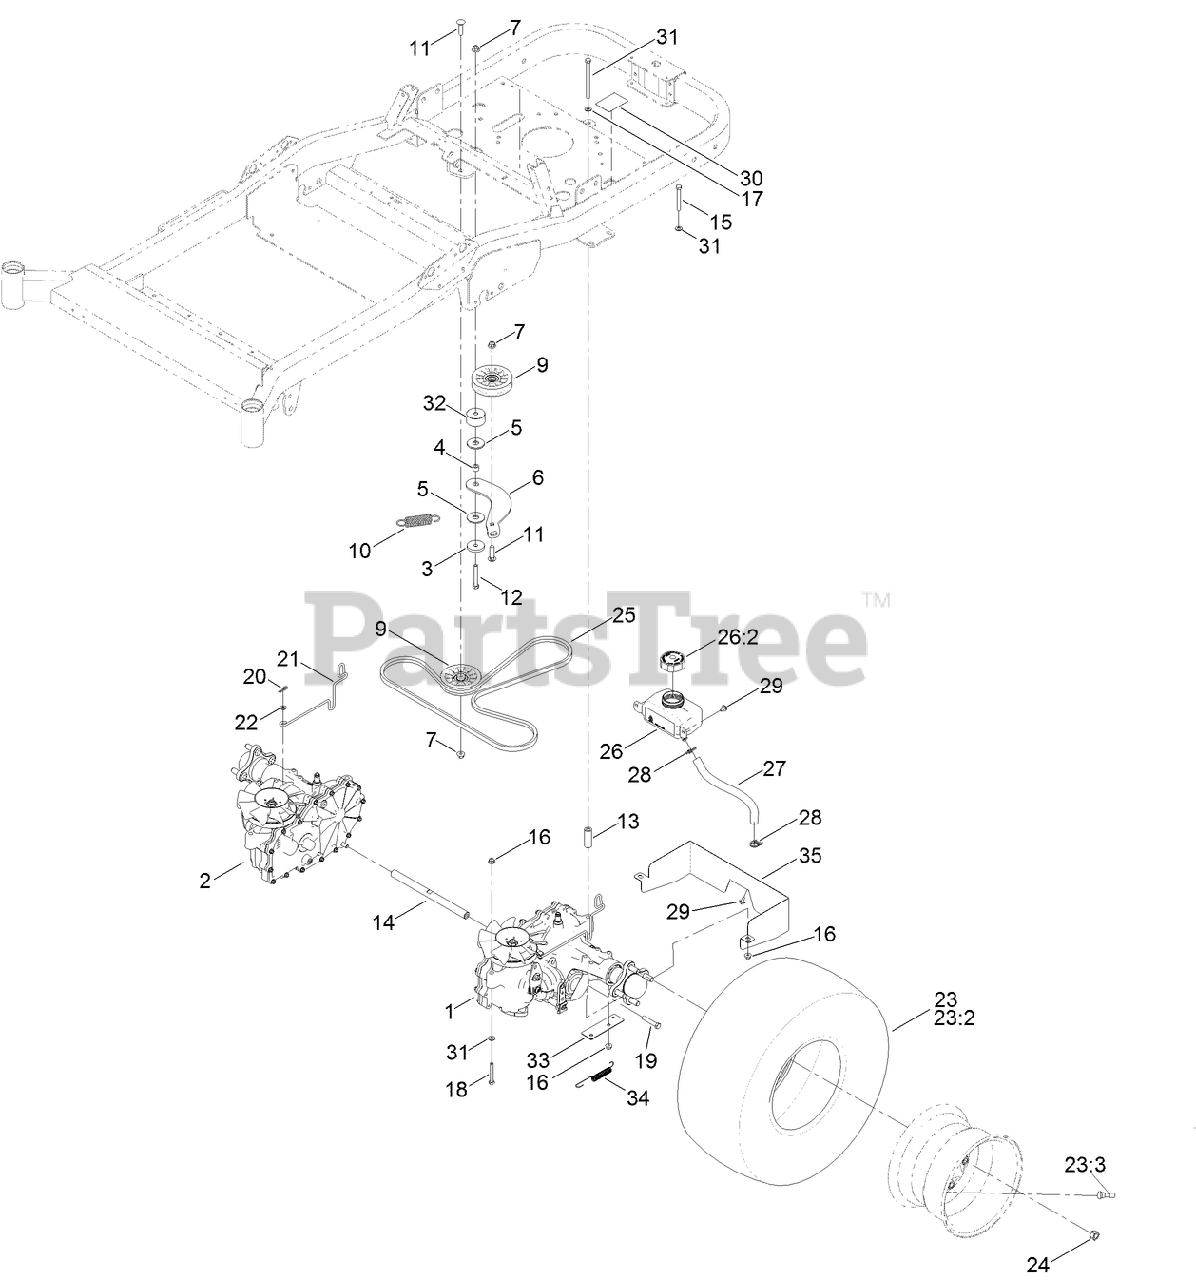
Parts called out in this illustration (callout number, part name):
1	LH HYDRO TRANSMISSION ASM
2	RH HYDRO TRANSMISSION ASM
3	WASHER-PLAIN
4	SPACER
5	WASHER-FRICTION, COMPOSITE
6	ARM-IDLER
7	NUT-HF, NI
9	PULLEY-IDLER, FLAT
10	SPRING-EXTENSION
11	SCREW-CARR
12	SCREW-HH
13	SPACER-HYDRO
14	SHAFT-CROSS, HYDRO
15	SCREW-HH
16	NUT-HF, NI
17	SCREW-HH
18	SCREW-HH
19	SCREW-HH
20	PIN-COTTER
21	ROD-BYPASS
22	WASHER
23	TIRE AND WHEEL ASM
24	NUT-LUG
25	V-BELT
26	HYD RESERVIOR ASM
26:2	CAP-RESERVOIR, HYD
27	HOSE-OVERFLOW
28	CLAMP-HOSE
29	SCREW-HHFTF
30	DECAL-BYPASS
31	WASHER-PLAIN
32	SPACER
33	PLATE-SPRING
34	SPRING-EXTENSION
35	GUARD, REAR
